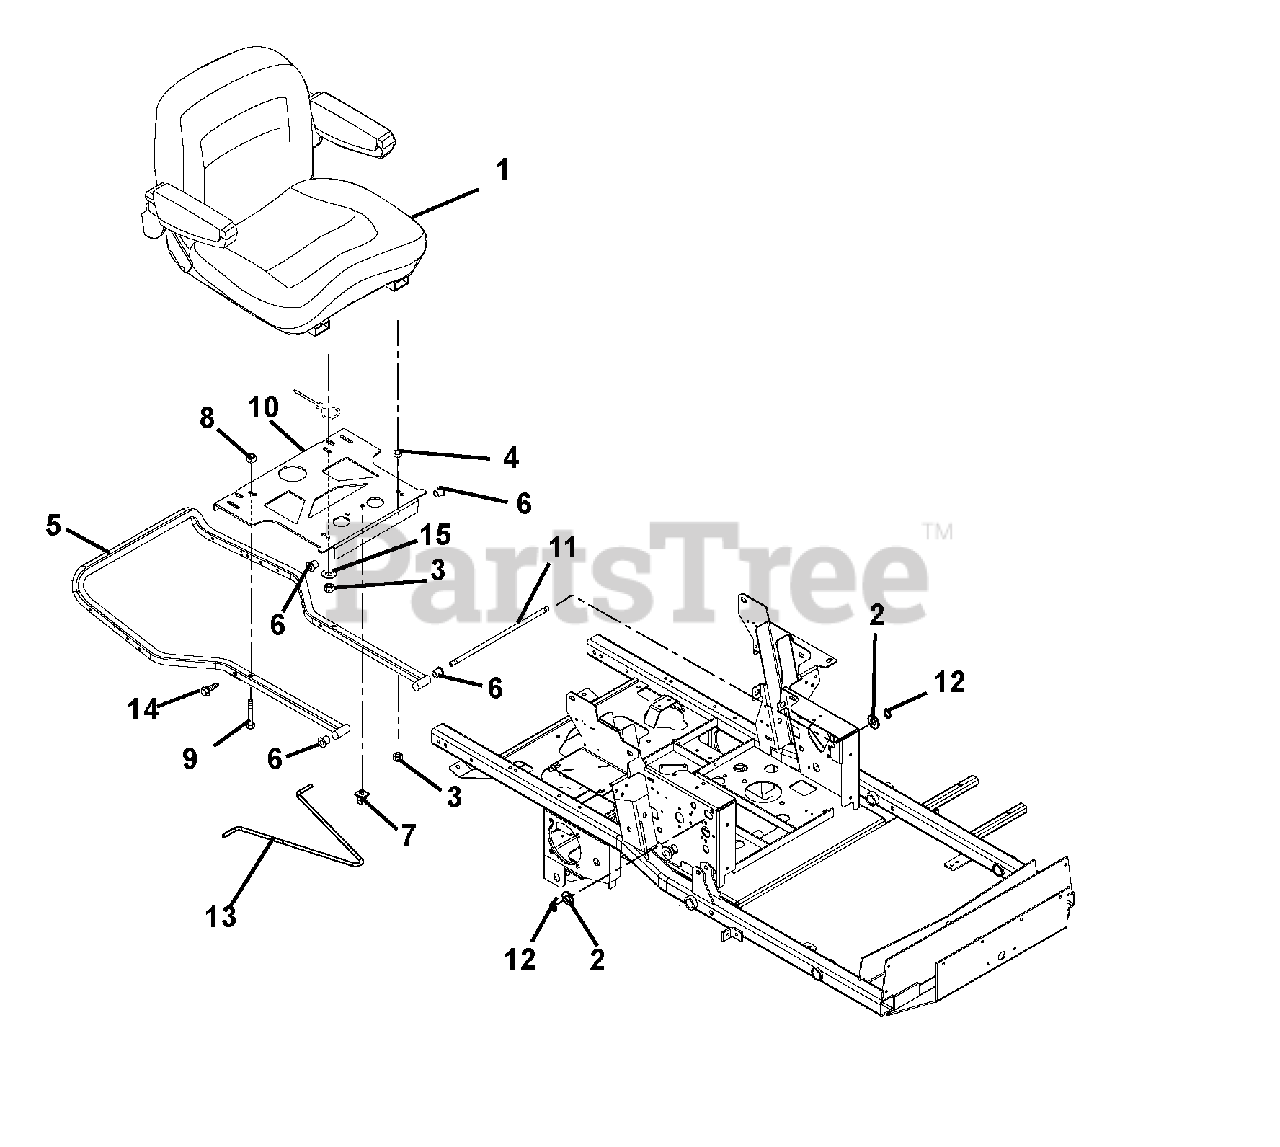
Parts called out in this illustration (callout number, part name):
1	Seat
2	Washer, Flat Steel .531 x 1.06 x .095
3	Nut, Locking Top Flange .31-18
4	Bushing, Sleeve .377 x .624 x .235
5	Weldment, Hood Frame
6	Bushing-Flange .515 x .750 x .745 x 1.00
8	Nut, Locking Top Flange .38-16
9	Bolt, Rib Neck .38-16 x 1.50
10	Weldment, Seat Pivot Plate
11	Rod, Seat Frame Pivot
12	Ring, Retaining External .500 x .050
13	Rod, Prop
14	Screw, Tapping .25-20 x .50 Hex Washer Head
15	Washer, Flat Steel .344 x 1.25 x .135
